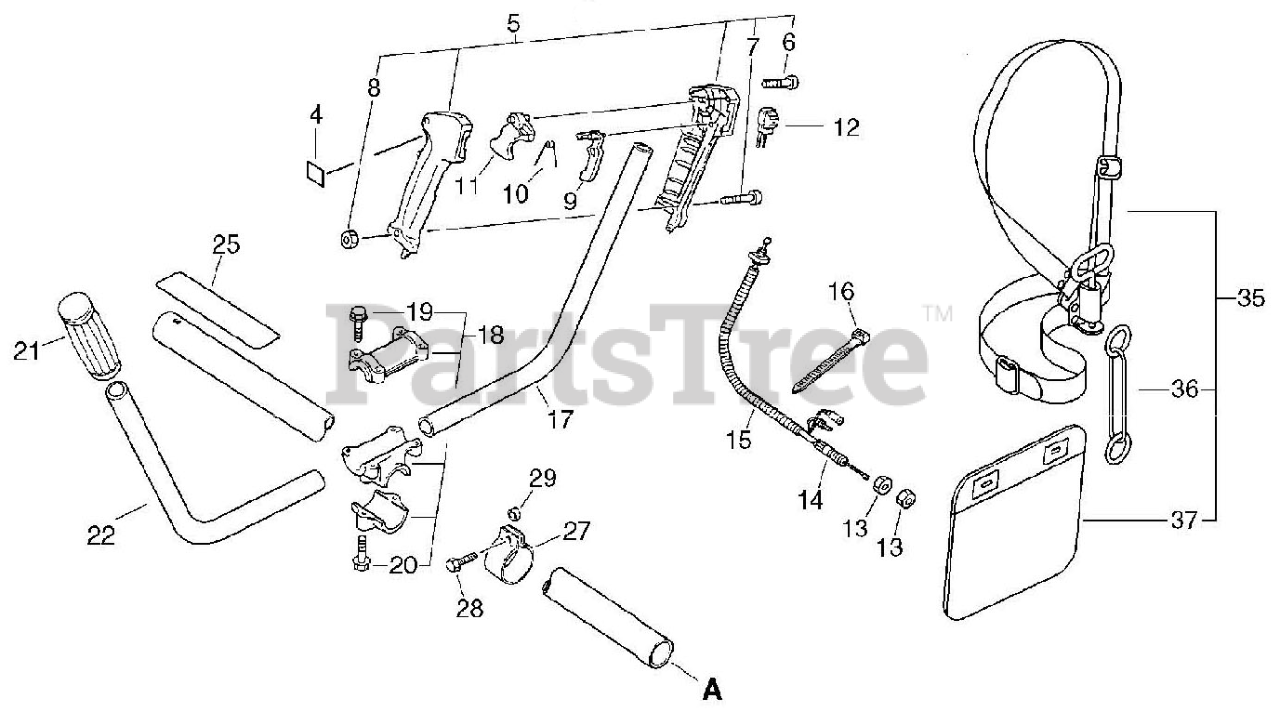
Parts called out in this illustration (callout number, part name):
4	LABEL - STOP
5	CONTROL HANDLE KIT
6	SCREW 3×25
7	SCREW 5×30
9	LOCKOUT, THROTTLE
10	SPRING, TORSION
11	TRIGGER, THROTTLE
12	IGNITION SWITCH ASSY
14	CABLE, THROTTLE
15	TUBE
16	STRAP, TIE
17	HANDLE, FRONT
18	BRACKET, HANDLE
19	BOLT - 5×25
20	BOLT - 6×30
21	GRIP, HANDLE
22	HANDLE, LEFT
25	LABEL - CAUTION - ISO
28	BOLT 5×18
29	SPACER, GUARD
35	HARNESS ASSY, SHOULDER
37	PAD, HIP
